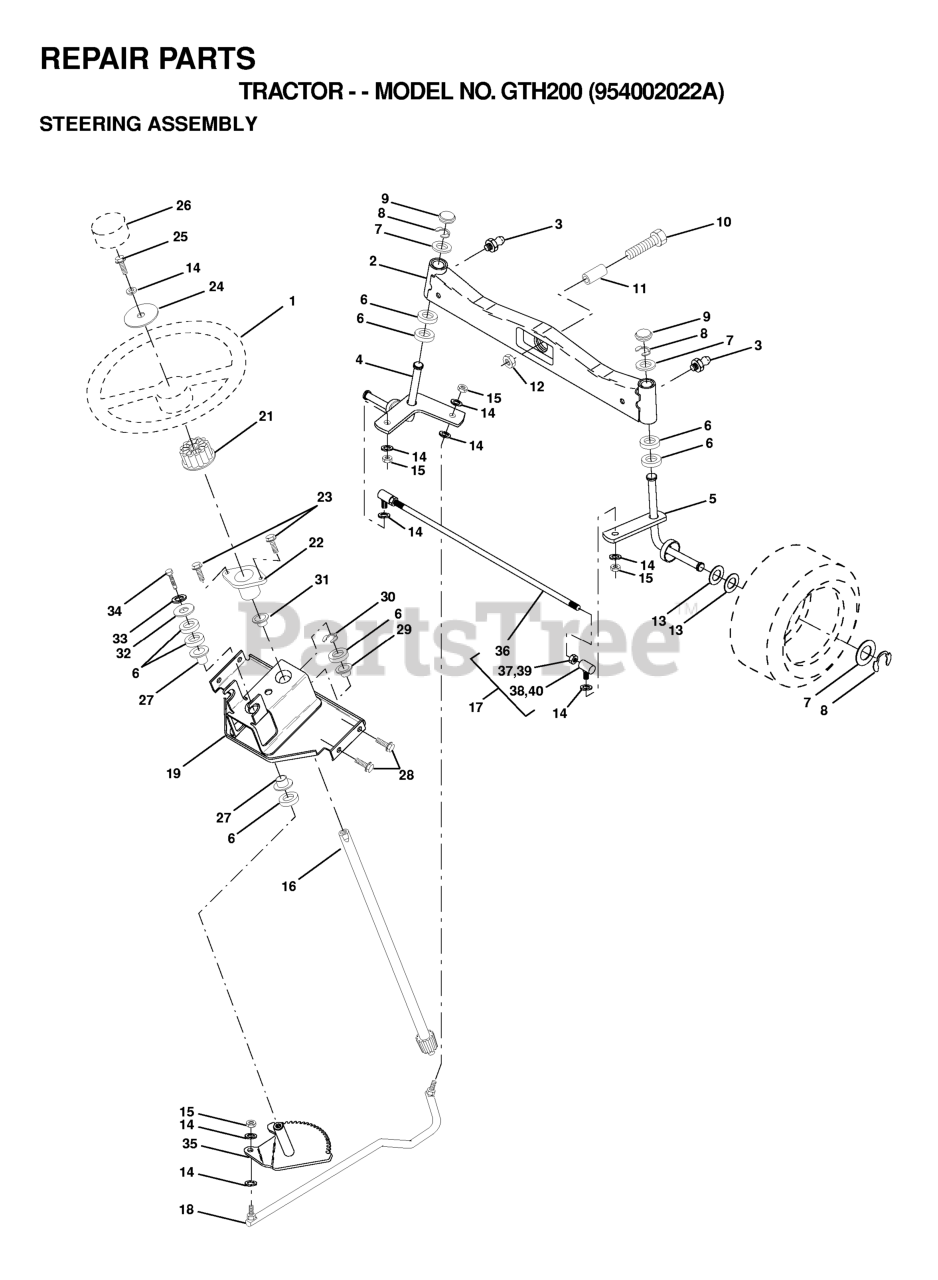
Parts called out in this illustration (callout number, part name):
1	STEERING WHEEL
2	FRONT AXLE ASSY
3	ZERK M
4	SPINDLE ASSY LH
5	SPINDLE ASSY RH
6	BEARING RACE
9	CAP.SPINDLE.BLACK
10	Bolt, Hex 5/8 -11 x 2 - 3/4 Gr. 5
11	TUBE, PIVOT AXLE
12	NUT-LOC,FLANGE LT
14	WASHER, LOCK 3/8
15	NUT
16	SHAFT ASM, STEERING
17	ROD ASSY/TIE BALL
18	DRAGLINK-BALL JOINT SOLID
19	SUPPORT ARM, STEERING VGT
21	ADAPTER LT
22	BUSHING LT
23	SCREW LT
24	WASHER T
26	INSERT,STR WHEEL
27	BRNG T
28	SCREW
29	BEARING-FLANGE GT
30	Ring, Klip Truarc #5304-75
31	BUSHING.NYLINER.
33	WASHER.LOCK.HVY.HLCL.SPR.5/16
34	BOLT
35	GEAR.ASM.SECTOR.
36	TIE ROD
38	JOINT
